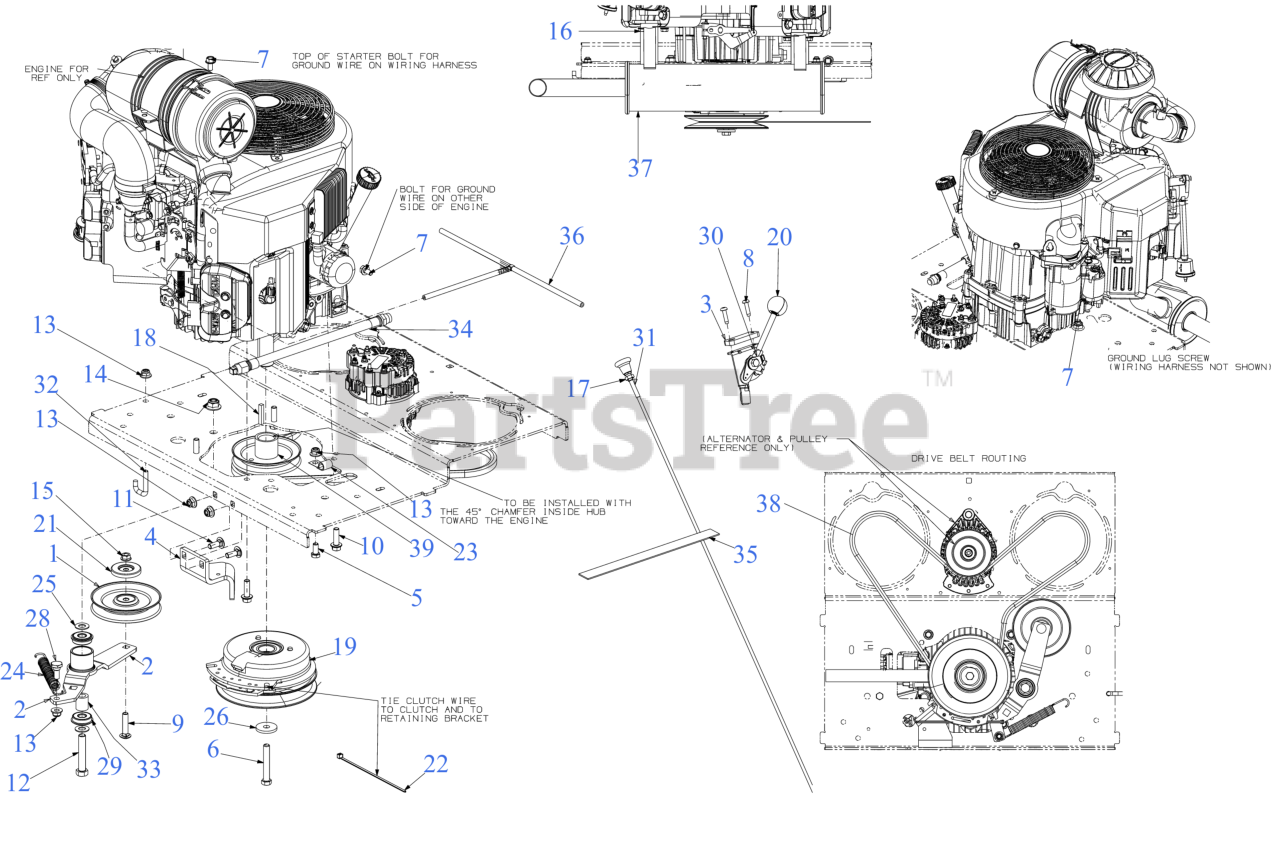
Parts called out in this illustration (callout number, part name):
1	V-IDLER PULLEY
2	IDLER ARM BRACKET
4	CLUTCH RETAINER BRACKET
5	HEX SCREW 3/8-16 x .75
6	SCREW 7/16-20:2.75 GR5
7	SCREW M8 x 1.25 x 16MM GR8.8
8	SCREW 1/4-20 x 1.0
9	CARRIAGE BOLT 3/8-16 x 1.75 GR5
10	SCREW 3/8-16 x 1.25 GR5
11	CARRIAGE BOLT 3/8-16 x 1.00 GR5
12	SCREW 1/2-13 x 2.75 GR5
15	HEX LOCK NUT
16	HEX FLANGE NUT
17	HEX JAM NUT 3/8X24
18	SQUARE KEY 1/4 x 1.50
19	ELECTRIC PTO CLUTCH
21	PULLEY CAP
22	7" CABLE TIE
23	J TYPE CLIP
24	EXTENTION SRING .75 DIA. x 6.85
25	FLAT WASHER .510 x .995
28	SHOULDER SCREW
29	ROLLER BEARING .5X1.37X.44
30	THROTTLE CABLE 59"
31	CHOKE CABLE
32	ROD SPRING HOOK
33	SPACER 0.51 x 0.88 x 1.00
34	OIL DRAIN HOSE
35	HEAT SHIELD 24"
36	ROLLOVER VENT HOSE ASSEMBLY
37	MUFFLER - KAWASAKI 1000
38	BELT AA x 63.25"
39	PULLEY - PUMP DRIVE
